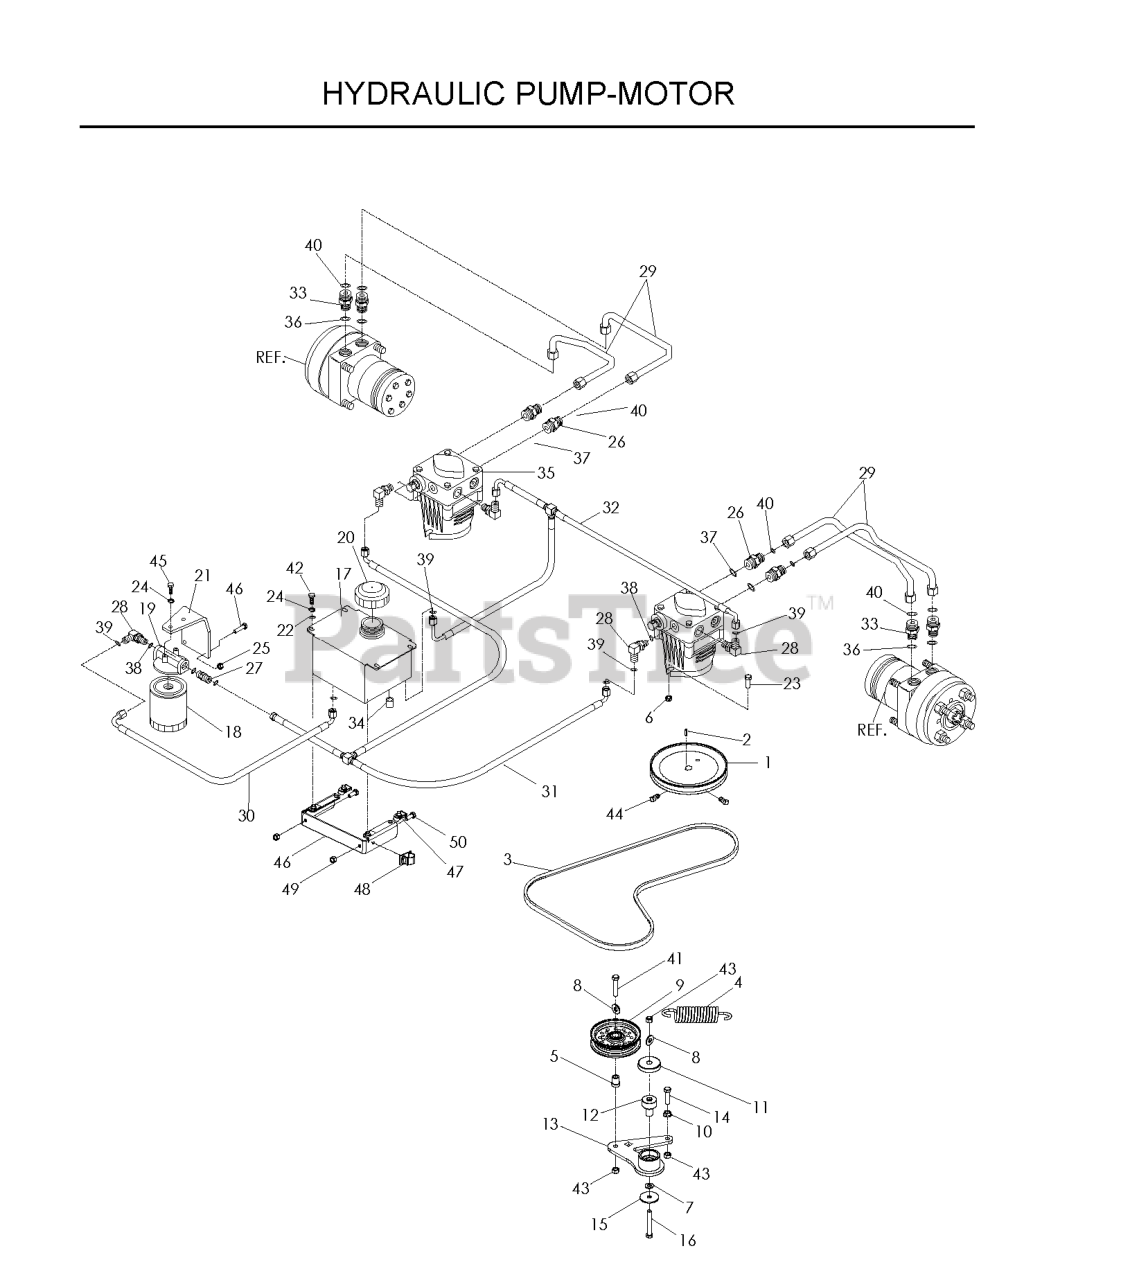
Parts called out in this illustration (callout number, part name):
2	KEY 5 MM SQ X 25 MM
3	PUMP BELT
5	BUSHING, IDLER FLANGE
6	NUT 3/8C CENTERBLOCK
7	WASHER 3/8 SAE FLAT
8	WASHER 3/8 FLAT
9	IDLER PULLEY
10	NUT 3/8C WHIZ
11	SHIELD, DUST
12	PIVOT, BEARING
13	ARM, IDLER - W/BEARINGS
14	HCS 3/8C X 1 1/2
15	WASHER, 3/8 SPEC
16	HEX SCREW 3/8-20 X 2.75
18	HYDRAULIC OIL FILTER
19	FILTER HEAD
20	HYDRAULIC CAP
21	OIL FILTER BRKT
22	WASHER 1/4 FLAT
23	4CS 3/8C X 1 SERRATED HEAD
24	LOCKWASHER 1/4"
25	NUT.1/4-20.HEX.NYLOC.ZD
26	FITTING, STRAIGHT F6400-8-8-0
27	HYDRAULIC FITTING
28	ELBOW, F6801-6-6-0 90 DEGREE
29	HYDRAULIC HOSE
31	T-ASSEMBLY
34	NUT 9/16-18 JIC CAP
35	HG_PUMP, 10CC W/O FAN
41	HCS 3/8C X 2
42	HCS 1/4C X 3/4 HCS
43	NUT 3/8-16 NYLOC
44	SCREW 5/16C X 5/8 SQ HEAD
45	HCS 1/4C X 5/8
46	TANK MOUNT
47	1/4C - U TYPE RETAINER
48	PUSH-MOUNT WIRE CLIP
49	NUT 5/16 NYLOC
50	HCS 5/16C X 3/4
